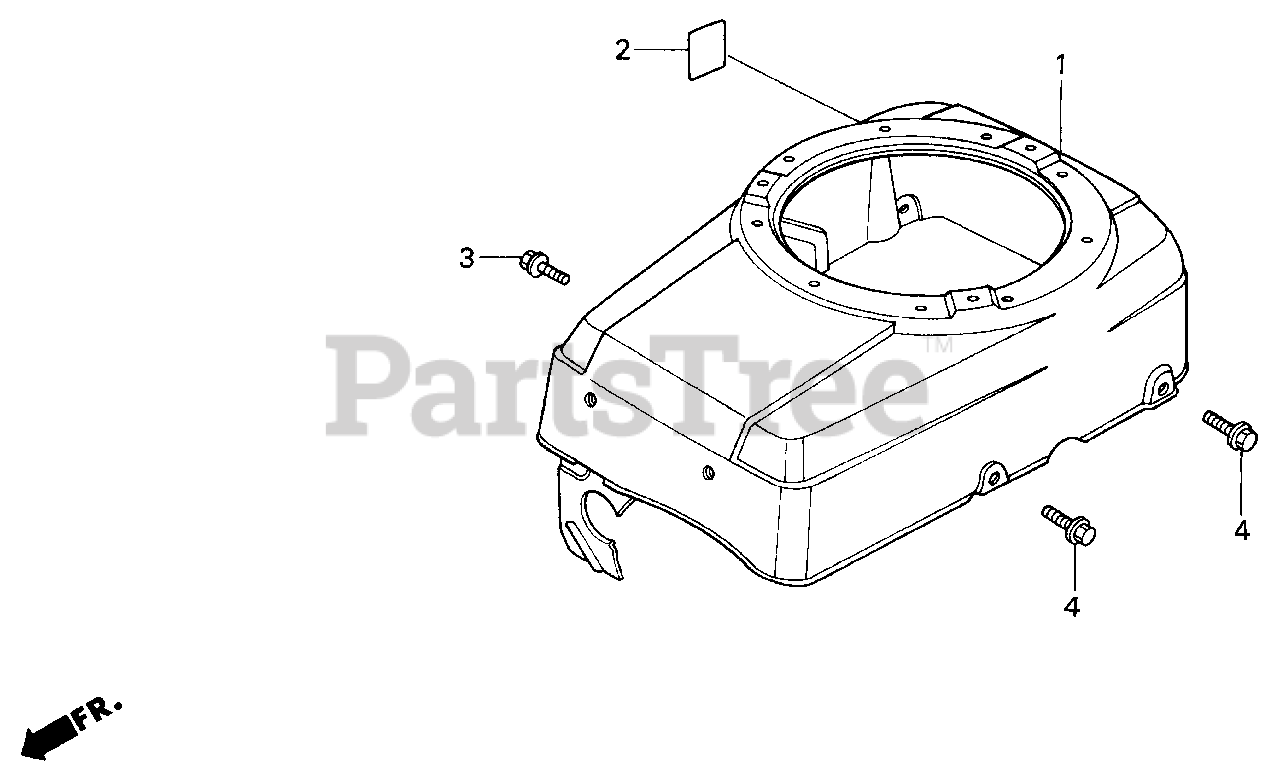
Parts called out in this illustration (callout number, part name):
1	COVER, FAN
2	MARK, OIL CAUTION
3	BOLT, FLANGE (6X12) (CT200)
4	BOLT, FLANGE (8X16)
